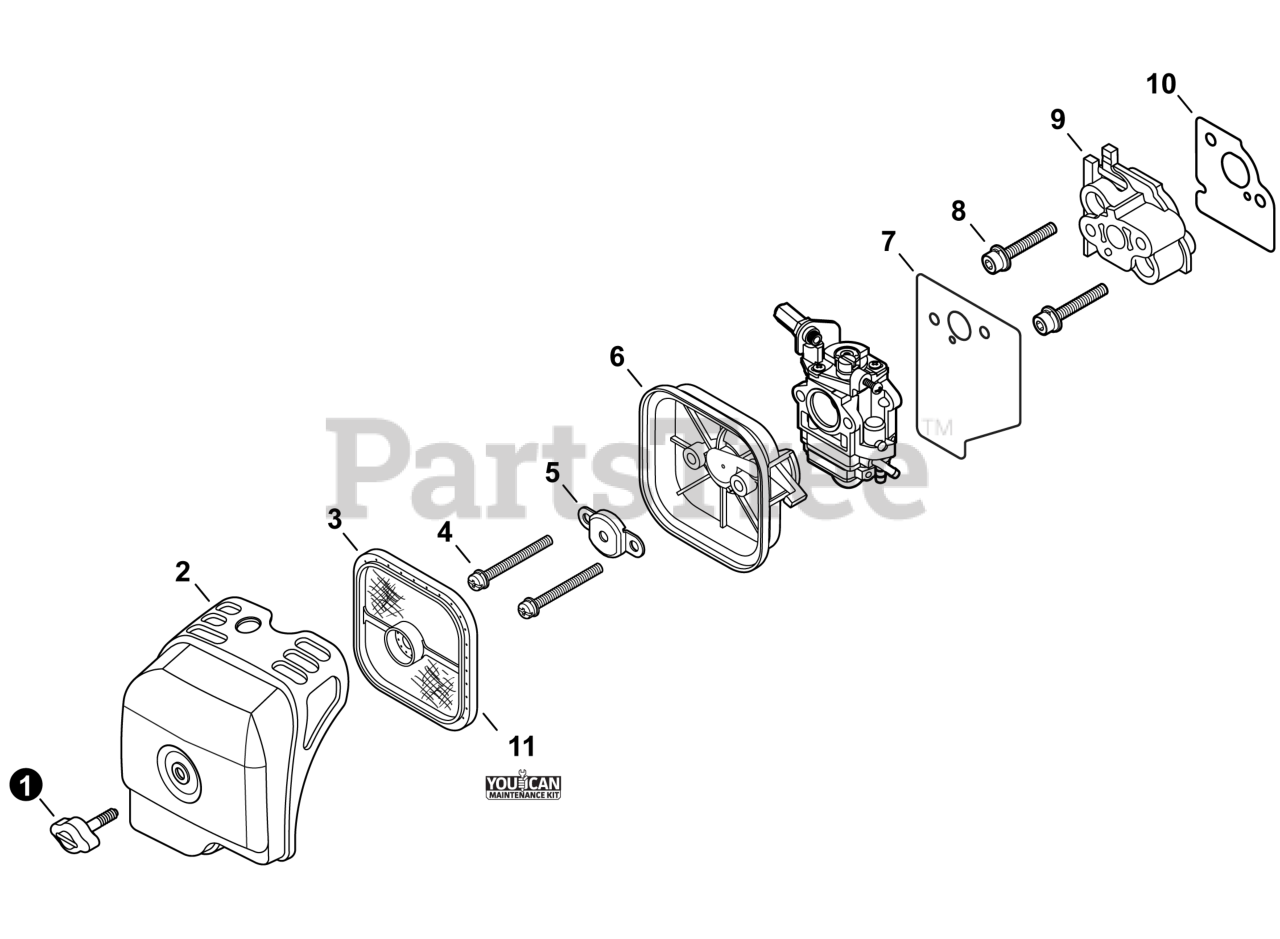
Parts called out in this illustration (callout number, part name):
1	THUMBSCREW
2	COVER, AIR FILTER
3	FILTER, AIR - DOUBLE LAYER
4	SCREW 5×60
5	PLATE, PREVENT
6	CASE ASSY, AIR FILTER
7	GASKET, CARBURETOR
8	BOLT M5×30
9	INSULATOR
10	HEAT SHIELD, INTAKE
11	TUNE-UP KIT - YOUCANT
